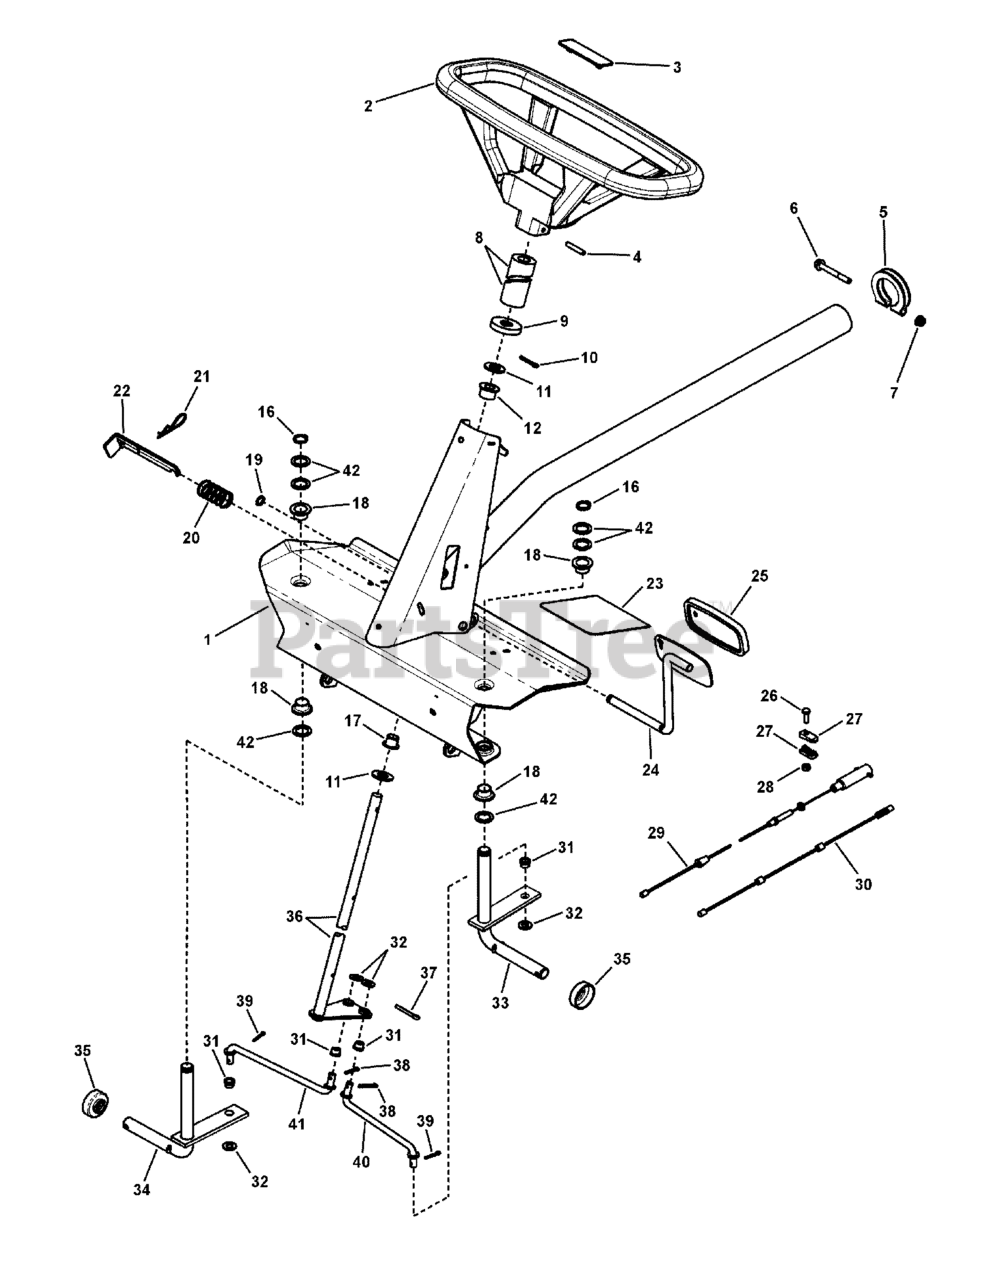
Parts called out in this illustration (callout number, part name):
1	WELDMENT, Front Axle, Narrow
2	ASSEMBLY, Steering Wheel
3	PLATE, Center, Steering Wheel
4	ROLL PIN, 1/4 x 1-1/2"
5	TUBE CLAMP
6	SCREW, 5/16-24 x 2-1/2" Hex Head Cap, GR 5
7	NUT, 5/16-24 Flange Lock
8	FOAM COVER, Steering Shaft
9	COVER, Steering Shaft
10	PIN, 3/16 x 1" Cotter
11	WASHER, .66 x 1.31 x .09 Flat
12	BUSHING, Nylon
16	RING, 5/8" External Retaining
17	BUSHING, Nylon
18	BEARING, Nylon
19	RING, 1/2" External Retaining, Heavy Duty
20	SPRING, Parking Brake Latch
21	HAIR PIN, 2-1/4"
22	LATCH, Parking Brake
23	FOOT PAD, Short, 5.5" x 4.7"
24	WELDMENT, Clutch Pedal
25	PAD, Pedal
26	SCREW, 1/4-20 x 3/4" Hex Head Cap, GR 5
27	CONNECTOR, Cable
28	NUT, 1/4-20 Hex Center Lock, GR 5 or B
29	CABLE, Brake, Snap-In
30	CABLE, Clutch/Brake, 54.32" long
31	BUSHING, Tie Rod
32	WASHER, 3/8" Flat SAE
33	WELDMENT, King Pin, Left Hand
34	WELDMENT, King Pin, Right Hand
35	CAP, Dust
36	WELDMENT, Steering Shaft
37	PIN, 3/16 x 1-1/2" Cotter
38	PIN, 5/32 x 1" Cotter
39	PIN, 1/8 x 3/4" Cotter
40	TIE ROD, Left Hand (7.41" long)
41	TIE ROD, Right Hand (7.41" long)
42	WASHER, .77 x 1.13 x .06 Flat
